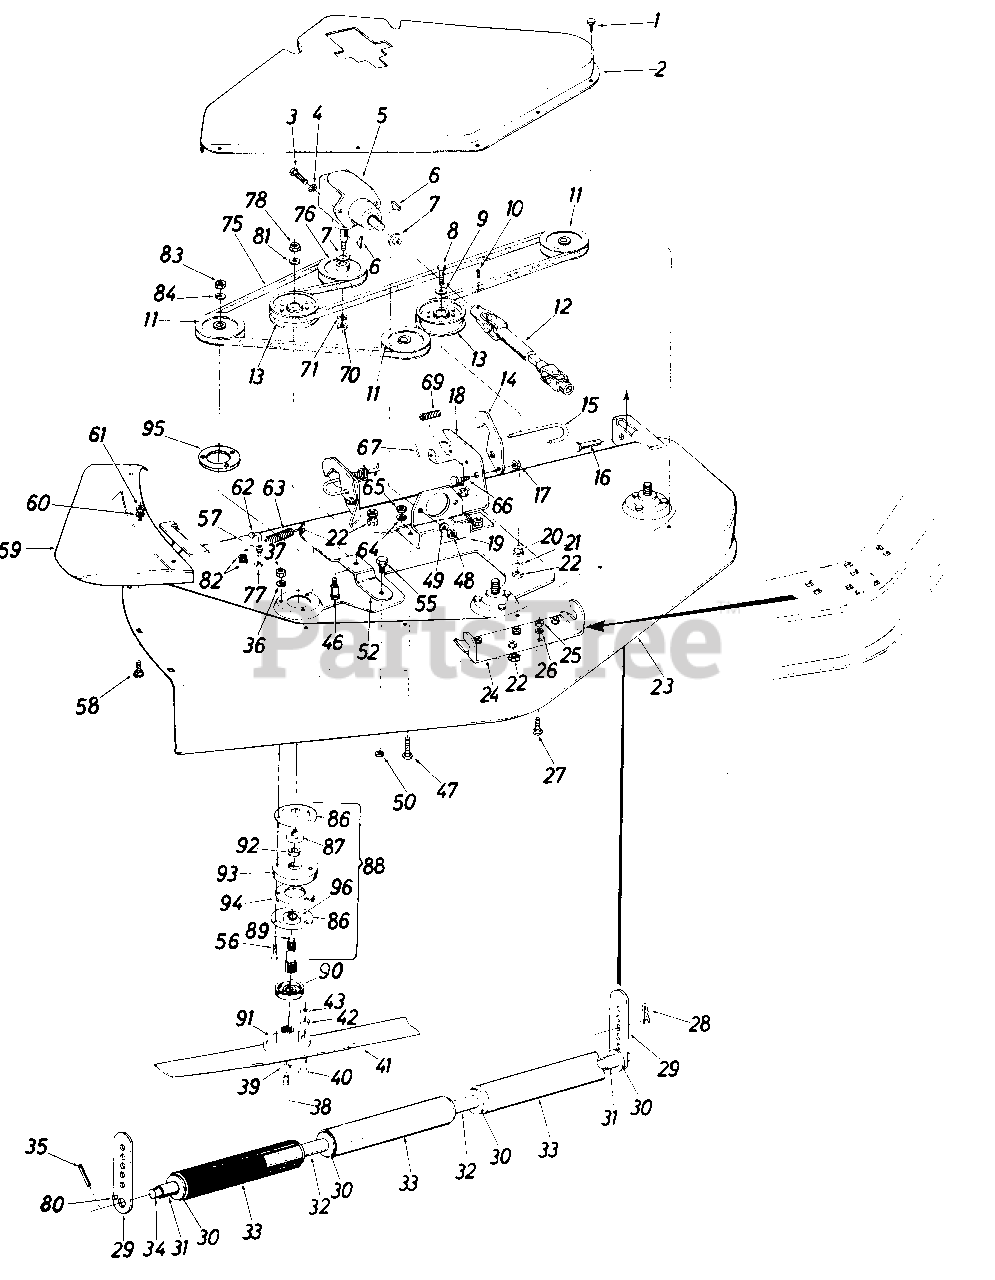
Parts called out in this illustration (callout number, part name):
1	Hex B Tap Scr. 1/4-20 x .38" Lg.
4	Ext. L-Wash. 3/8" Scr.*
5	Right Angle Drive
6	#9 Hi-Pro Key 3/16 x 3/4" Dia.
7	Fl-Wash. 29/32 I.D.
8	Hex Scr. 3/8-16 x 2.25" Lg.*
9	Fl-Wash. 3/8" I.D.
10	Sq. Hd Set Scr. 3/8-16 x .50" Lg. Cup
11	Deck Pulley
12	Universal Drive Shaft Ass'y.
13	Deck Idler Pulley
14	Hanger Lock
15	Release Pin
16	Clevis Pin .500 Dia.
17	Hex Cent. L-Nut 5/16-18 Thd.
21	L-Wash. 3/8" Scr.*
22	Hex Nut 3/8-16" Thd.*
26	L-Wash. 5/16" Scr.*
27	Carriage Bolt 5/16-18 x 1.00" Lg.*
28	Internal Cotter Pin
30	Fl-Wash. .75 I.D. x 1.5 O.D.
31	Spacer .758 I.D. x 1.25 O.D. x .530
34	Roller Shaft
35	Roll Pin 3/16 x 1.25
36	L-Wash. 5/16" Scr.*
37	Hex Cent. L-Nut 5/16-24 Thd.
38	Hex Scr. 3/8-24 x .75" Lg. Thd. Rolling
39	L-Wash. 3/8" Scr. H.D.
40	Hex Scr. 5/16-24 x l.OO" Lg.
41	Blade 17"
42	L-Wash . 5/16 " Scr.*
43	Hex Cent. L-Nut 5/16-24 Thd.
46	Hex Scr. 5/8-18x 1.31" Lg.
47	Carriage Bolt 5/16-18 x .75"
48	Hex Nut 3/8-16 Thd.*
49	L-Wash. 3/8" Scr.*
50	Hex Cent. L-Nut 7/16-14
56	Hex Scr. 5/16-24 x 1.50" Lg. (Grade 5)
57	Hex Nut 1/4-2 Thd.*
58	Carriage Bolt 5/16-18 x .75 Lg.*
60	L-Wash. 5/16" Scr.*
61	Hex Nut 5/16-18 Thcl.*
62	Hook Bolt
63	Extension Spring
64	L-Wash. 5/16" Scr.
65	Hex Nut 5/16-18 Thd.*
66	Shld. Scr.
67	Roll Pin 1/8" Dia.
69	Compression Spring
70	Hex Cent. L-Nut 5/8-18 Thd.
71	L-Wash. 5/8" Scr.*
75	"V"-Belt A Sect. 117" Lg.
76	Drive Pulley
77	Hex Cent. L-Nut 1/4-20 Thd.
78	Hex Cent. L-Jam Nut 5/8-18 Thd.
80	Spring Pin Spiral 1/4" Dia. 1.00" Lg.
81	Fl-Wash..62" I.D.
82	Ext. L-Wash. 1/4" Scr.*
83	Hex Jam Nut 5/8-18 Thd.
84	L-Wash. 5/8" I.D.*
86	Bearing Housing
87	Ball Bearing
88	Deck Spindle Ass'y.
89	Spindle
90	Bearing Shield
91	Blade Adapter
92	Spacer
93	Spindle Spacer Plate
94	Reinforcement Plate
95	Spindle Reinforcement Plate
96	Open Bearing Housing
